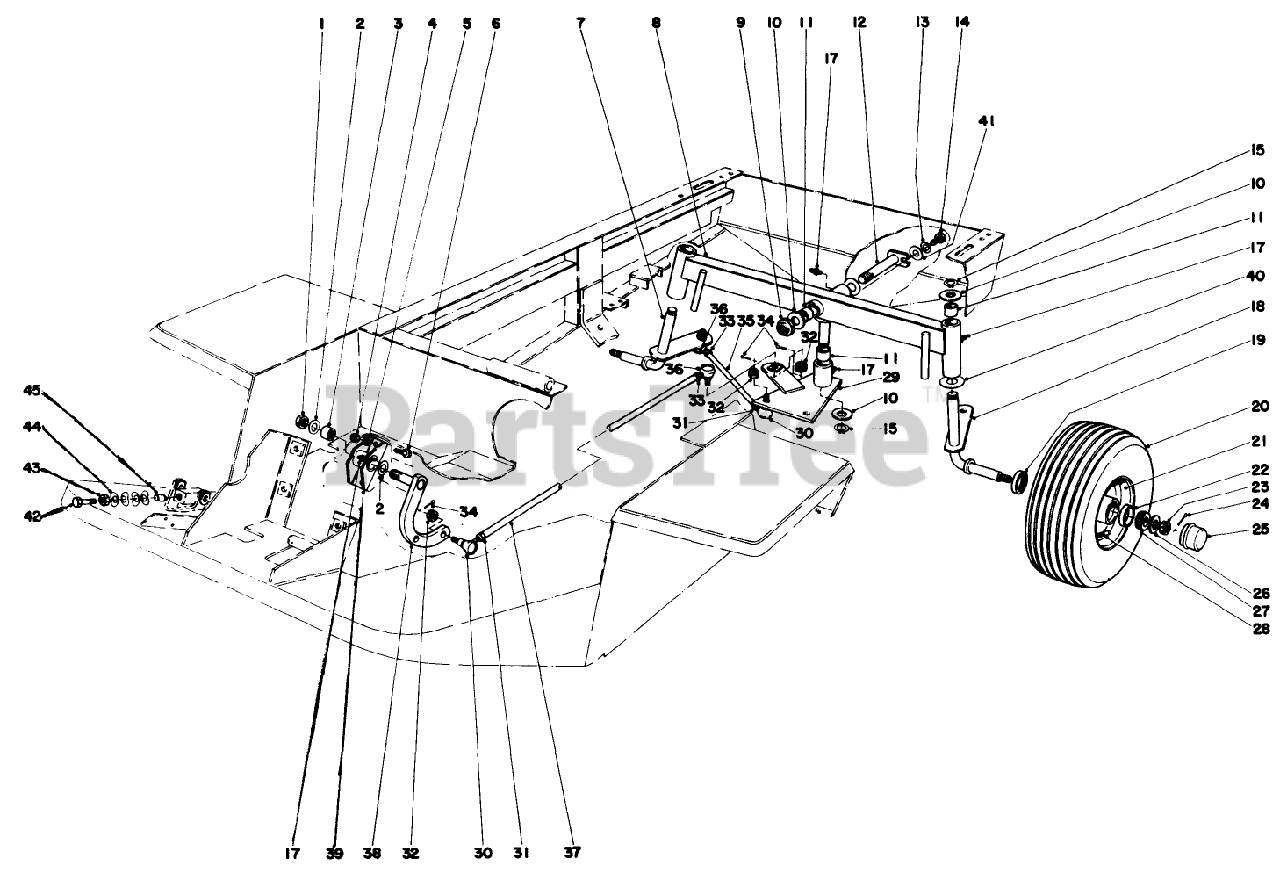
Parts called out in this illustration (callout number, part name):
1	NUT-LOCK, NI
2	THRUST WASHER
3	BEARING-NEEDLE
4	NUT-HEX
5	WASHER-LOCK
6	SCREW-HH
7	Spindle R.H.
8	Axle (Incl. Ref. #11 & 17)
9	NUT-LOCK, NI
10	WASHER-THRUST
11	BUSHING
12	Pin-RearAxle
13	WASHER-LOCK
14	SCREW-HH
15	RING-RETAINING
17	FITTING-GREASE
18	Spindle L.H.
20	Tire
21	WHEEL ASM
22	BEARING-CUP, TAPERED
23	NUT-HEX, SLOTTED
24	PIN-COTTER
25	CAP-DUST
26	WASHER-FLAT
27	BEARING-CONE, TAPERED
28	VALVE STEM AND CAP ASM
29	Steering Plate (Incl. Ref. #11 & 17)
30	Socket Assembly R.H. (Incl. Ref. # 32)
31	NUT-JAM
32	NUT-SLOTTED
33	NUT-HJ (LH THREAD)
34	PIN-COTTER
35	STRG TIE ROD R
36	Socket Assembly L.H. (Incl. Ref. #32)
37	REAR STRG TUBE PP
38	PIVOT ARM WA
39	Pivot Mount (Incl. Ref. #3 & 40)
40	WASHER-THRUST
41	WASHER-FLAT
42	SCREW-HH
43	NUT-JAM
44	Belleville Washer
45	PIN-PEDAL
